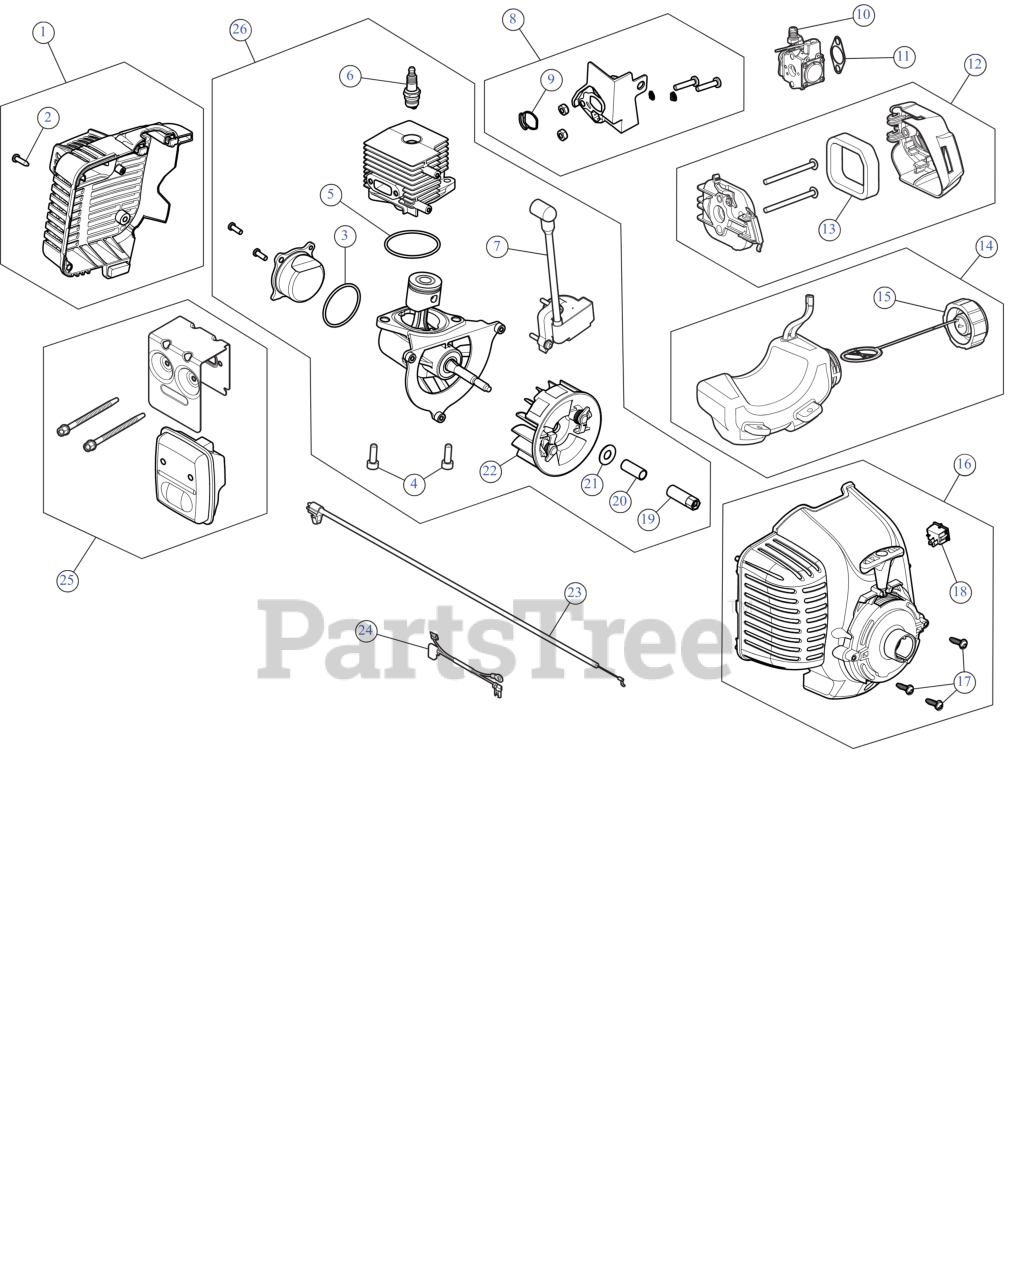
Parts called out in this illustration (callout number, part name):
1	HOUSING ASSEMBLY RR
2	SCREW, #8-16X.750 PH
3	O-RING SEAL CRANKCASE
4	SCREW 5/16-18x3/4 T40
5	O-RING SEAL CYLINDER
6	SPARK PLUG
7	MODULE ASSEMBLY
8	INTAKE ASSEMBLY
9	INSL/CYL SEAL
10	CARB ASSEMBLY
11	GASKET CARB
12	AIRCLEANER COVER ASSEMBLY
13	AIR FLITER
14	FUEL TANK ASSEMBLY
15	FUEL CAP ASSEMBLY
16	STARTER HOUSING ASSEMBLY
17	SCREW #
18	SW, MOMENTARY ON/O
19	POWER SHAFT ADAPTER
20	SPACER CRANKSHAFT
21	FLAT WASHER
22	FLYWHEEL ASSEMBLY
23	THROTTLE CABLE
24	WIRE LEAD
25	MUFFLER ASSEMBLY
26	SHORT BLOCK
